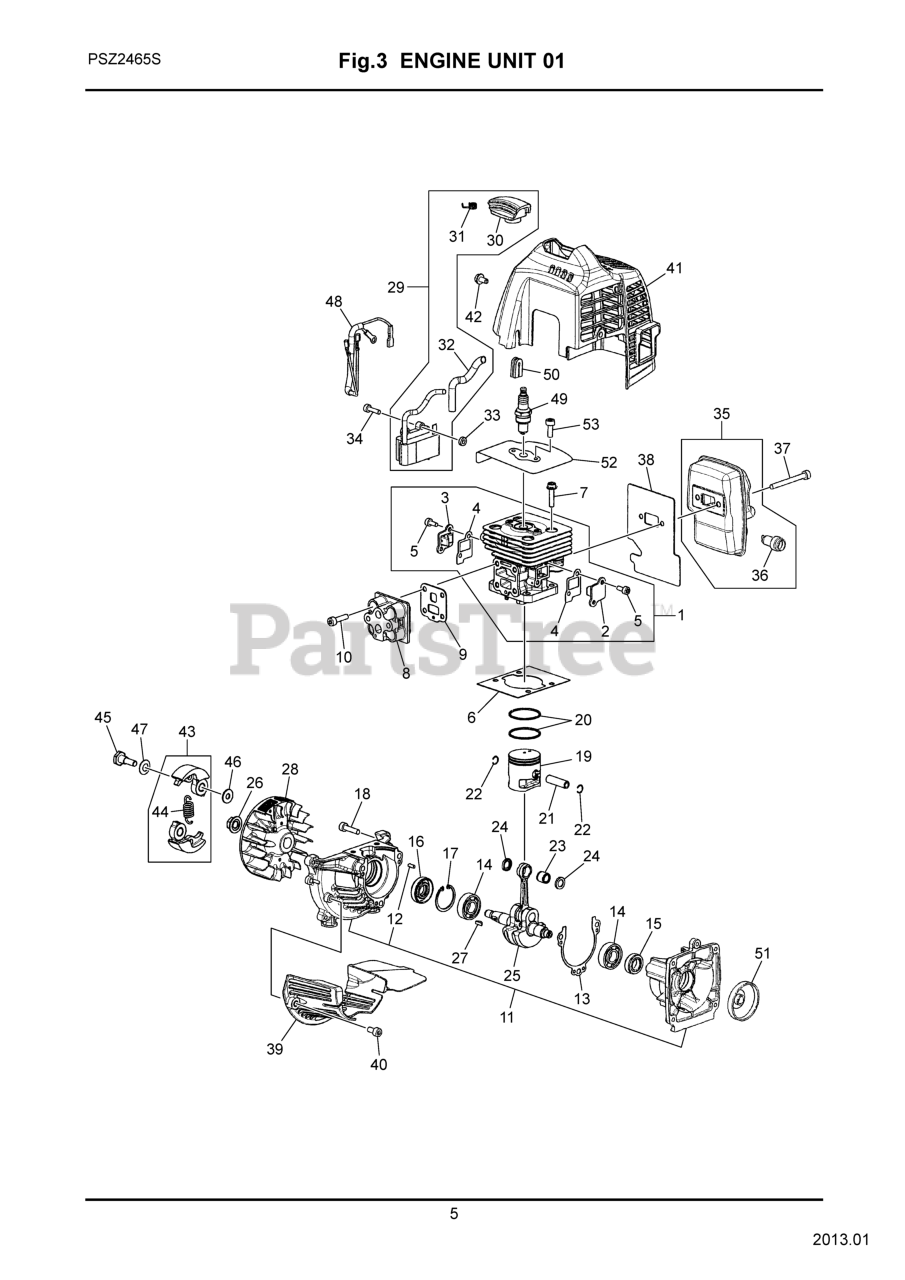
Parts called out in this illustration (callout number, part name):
1	CYLINDER COMP
2	COVER TR(S)
3	COVER TR(F)
4	GASKET, TR
5	BOLT
6	GASKET, BASE
7	BOLT
8	INSULATOR
9	INSULATOR GASKET(R-848F0814B0)
10	BOLT TORX
11	CRANKCASE-C
12	PIN
13	GASKET, CASE
16	SEAL
21	PIN
25	CRANKSHAFT-C
26	NUT
27	KEY
29	COIL ASSY
33	SPACER
36	ARRESTER
38	GASKET, MUFFLER
41	COVER, ENGINE
42	BOLT (RPLS T495051010-11)
43	SHOE COMP
48	CORD-COMP
49	SPARK PLUG CMR7H-10
